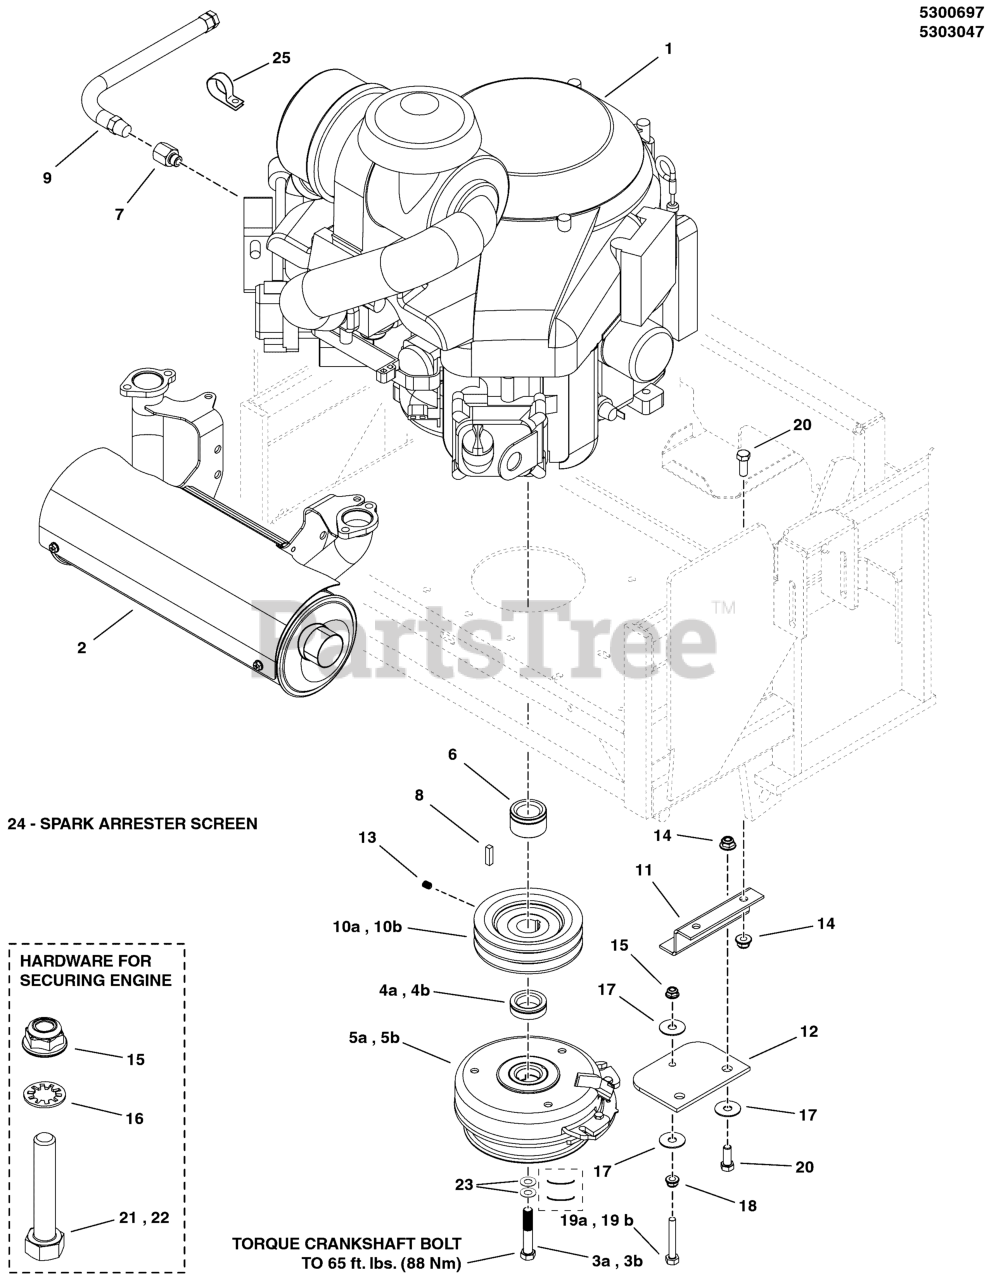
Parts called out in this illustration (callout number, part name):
1	ENGINE, BRIGGS & STRATTON
2	MUFFLER (Purchase from Engine Manufacturer)
6	SPACER, 1.13 X 1.75 X 1.09, PM
7	METRIC ADAPTER, M14-1.5" TO 3/8 NPTF
8	KEY, 1/4 SQ X 1
9	HOSE, OIL DRAIN
11	ANCHOR, CLUTCH - BLK
12	CLUTCH ANCHOR PAD
13	SET SCREW, 5/16-18 X 3/8, KNURL
14	NUT, 3/8-16 HEX NYLOCK FLANGE
15	NUT, 5/16-18 HEX NYLOCK FLANGE
16	WASHER, 5/16 INT. TOOTH LOCK
17	WASHER-3/8 FENDER
18	NUT, 5/16-18 HEX SERRATED FLANGE (SMALL)
20	BOLT, 3/8-16 X 1" GD5 CZ
21	BOLT, 5/16-18 X 2, GD5
22	BOLT, 5/16-18 X 1-3/4 GD5 YZ
23	BELLEVILLE WASHER 1.1875 X .442 X .089
24	SCREEN, ARRESTER
25	CLAMP, VINYL INSULATED
